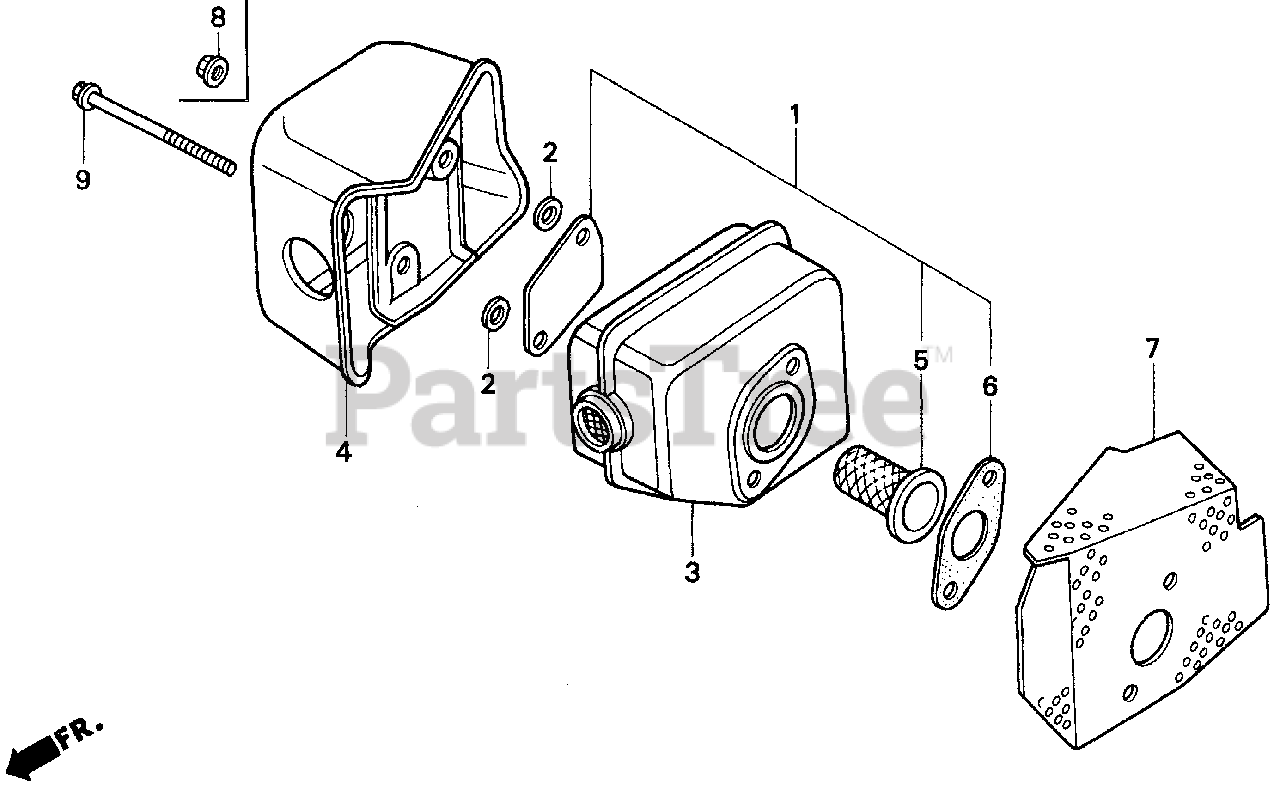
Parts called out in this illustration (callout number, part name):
1	ARRESTER KIT, SPARK
2	GASKET, PROTECTOR
3	MUFFLER
3	MUFFLER (FINLAND)
4	PROTECTOR, MUFFLER
5	ARRESTER KIT, SPARK
6	GASKET, MUFFLER
7	GASKET, MUFFLER
8	NUT, SELF-LOCK (6MM)
10	GUARD, MUFFLER
11	WASHER, PLAIN (6MM)
